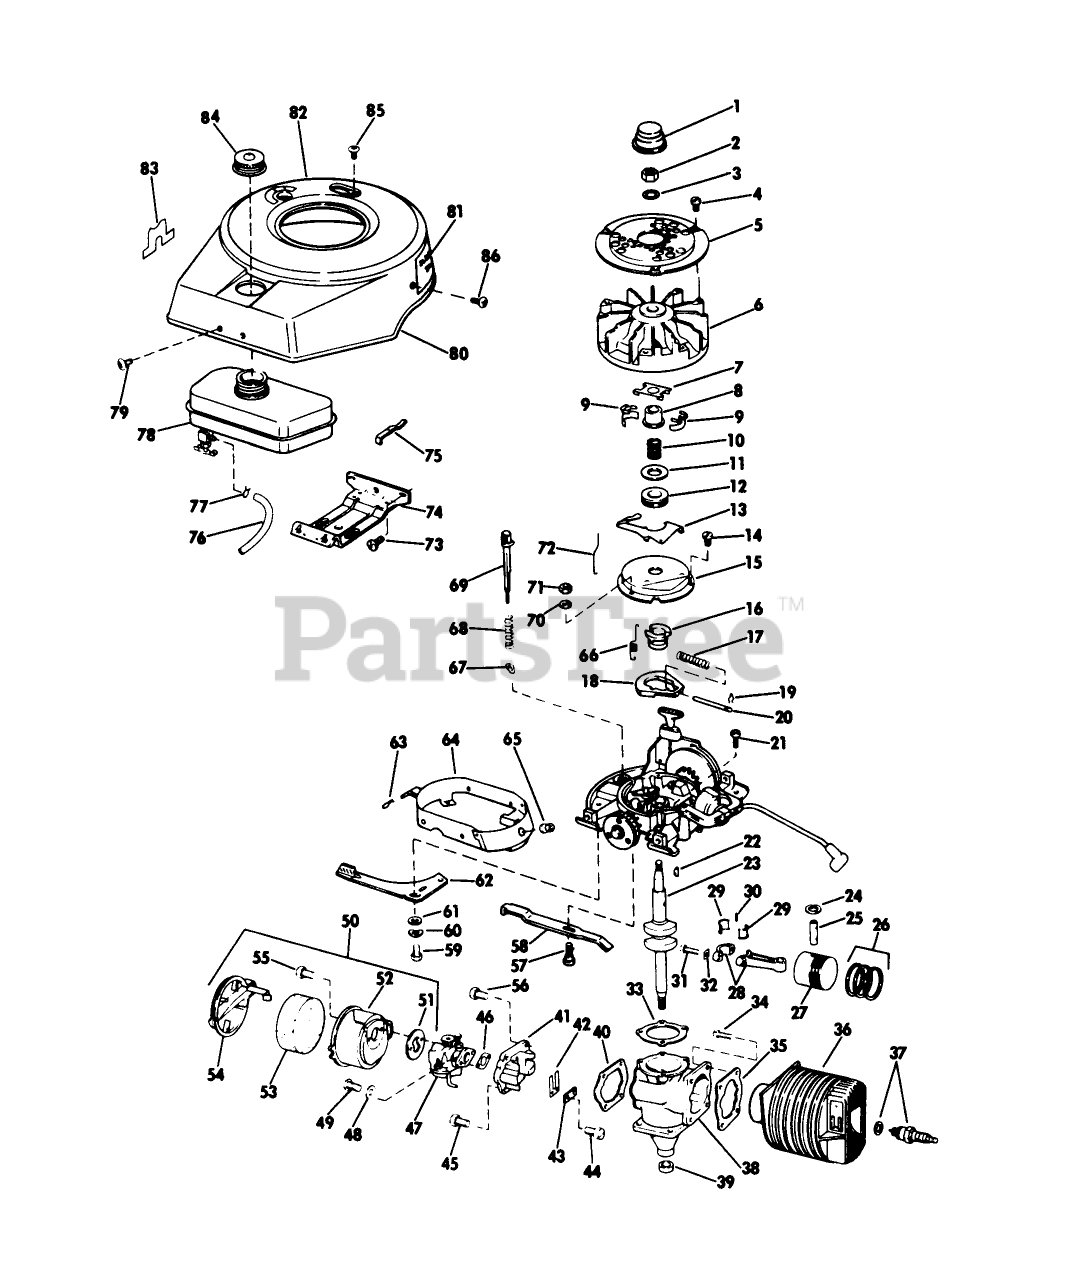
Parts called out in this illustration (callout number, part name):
8	COLLAR S
10	SPRING S
12	THRUST COLLAR S
13	LEVER-GOVERNOR S
14	SCREW S
15	DUST COVER S
16	SPARK ADV. S
17	SPARK ADV. SPRING S
18	FLYWEIGHT S
19	SPARK ADJ. SPRING
20	PIN,SPARK ADV. S
24	RING-RETAINING
29	LINER ASM
33	GASKET S
35	GASKET S
43	PLATE-BACKUP, REED
45	SCREW S
46	GASKET S
53	AIR FIL.ELEM S
55	SCREW S
56	SCREW S
65	NUT-CLIP
68	SPRING S
73	SCREW S
76	GAS LINE
77	CLAMP - HOSE S
80	Engine Cover Assembly
86	SCREW S
